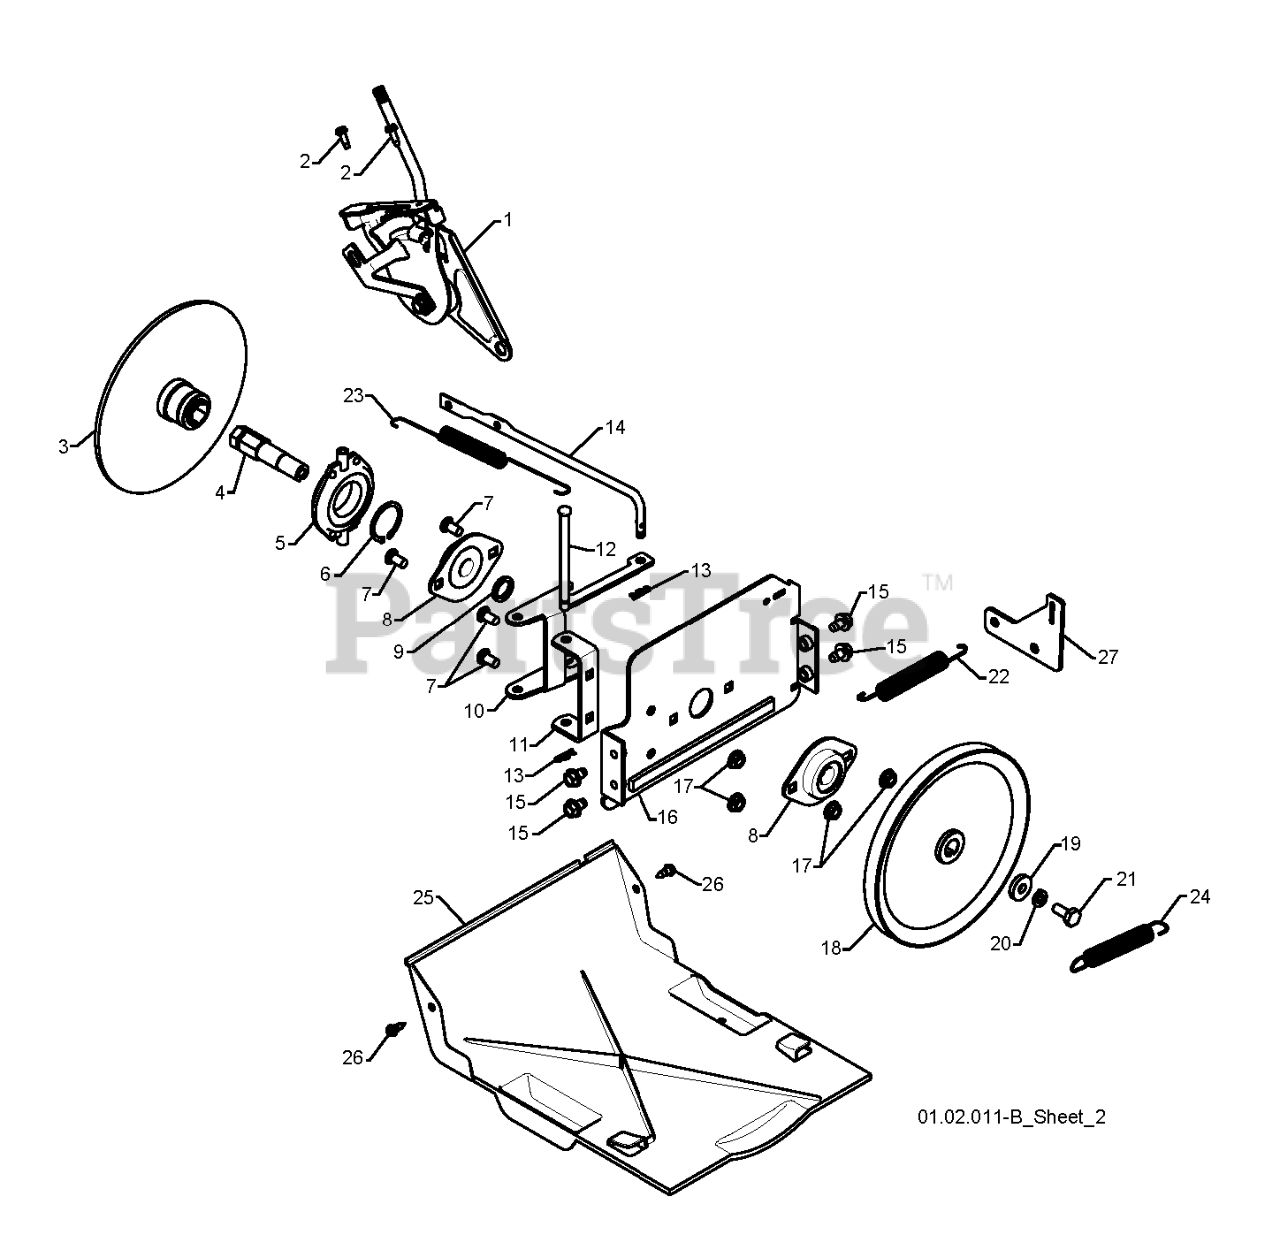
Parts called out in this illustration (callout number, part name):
1	HEAD ASSY SPEED
2	SCREW #10-24 X 5/8
3	DRIVE PLATE WELDMENT
4	SHAFT.HEX.SHORT
5	TRUNNION BEARING ASSY
6	RETAINING RING (2 2)(3 2)
7	BOLT
8	BEARING FLANGE
9	SPACER, BEARING
10	LEVER.SHIFTER.PLATE.BLACK
11	BRACKET, SHIFTER SUPPORT
12	PIN, PIVOT LEVER
13	RETAINER CLIP PM
14	ROD.CLUTCH.YELLOW.ZINC(VT)
15	Screw 5/16-18 x 1/2 Hex, Self Tapping 5/16-18 x 1/2
16	PLATE.DRIVE.MOUNTING.BLACK
17	NUT.FLANGE.5/16
18	PULLEY.TRACTION.7.75
19	WASHER, FLAT
20	WASHER.LOCK.HVY.HLCL.SPR.5/16
21	Screw, Hex Head 5/16-18 x 3/4
22	SPRING.TRACTION.IDLER
23	SPRING.RETURN
24	SPRING, BRAKE
25	PAN.BOTTOM.PLASTIC
26	SCREW, HEX HEAD, TAPPING
27	BRACKET.TRACTION.SPRING.
